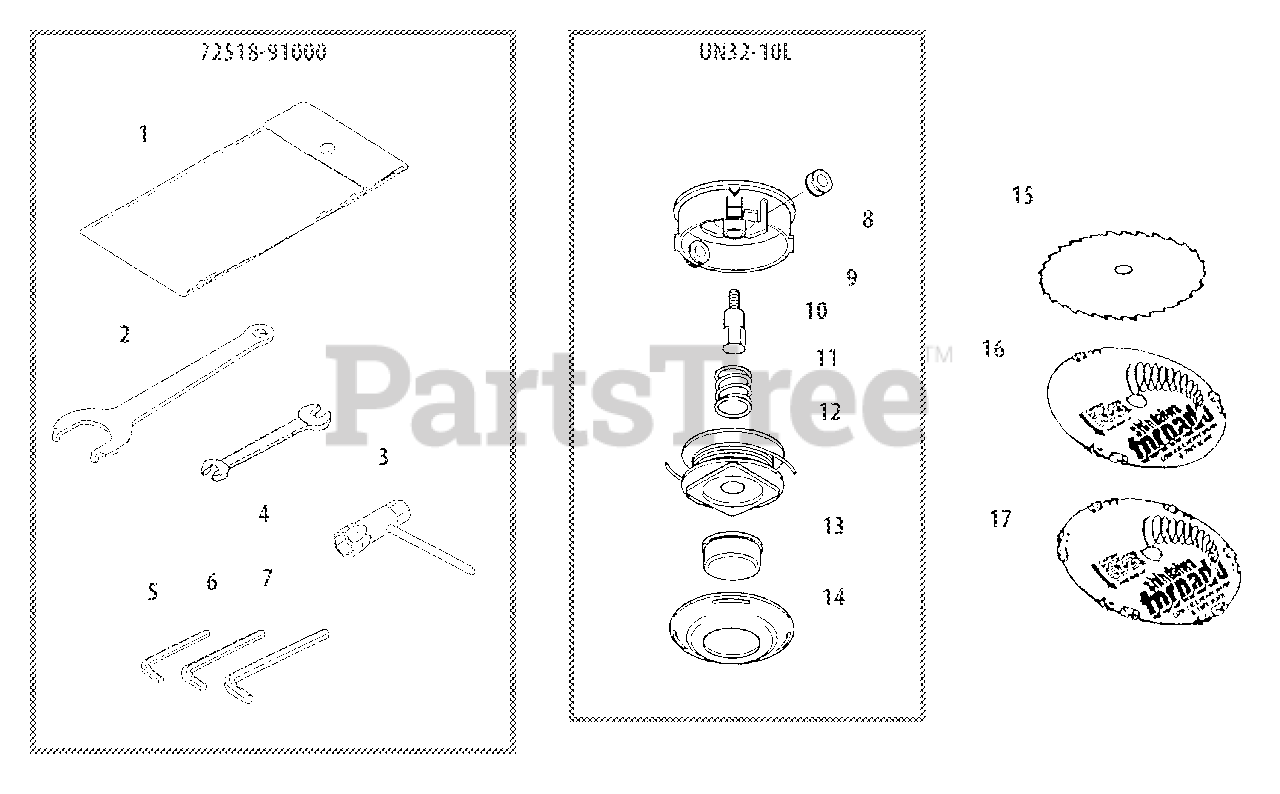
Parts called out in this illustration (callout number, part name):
1	BAG, TOOL
2	SPANNER
3	T-WRENCH
4	SPANNER - 8X10mm
5	HEX KEY - 3mm
6	HEX KEY - 4mm
7	HEX KEY - 6mm
10	SHAFT BOLT 10MM LH
15	BLADE - 30 TOOTH -- 9" (22cm)
16	BLADE - 6 TOOTH -- 9" (22cm)
17	BLADE - 12 TOOTH -- 9" (22cm)
72518-91000	TOOL KIT
UN32-10L	TRIMMER HEAD ASSY
